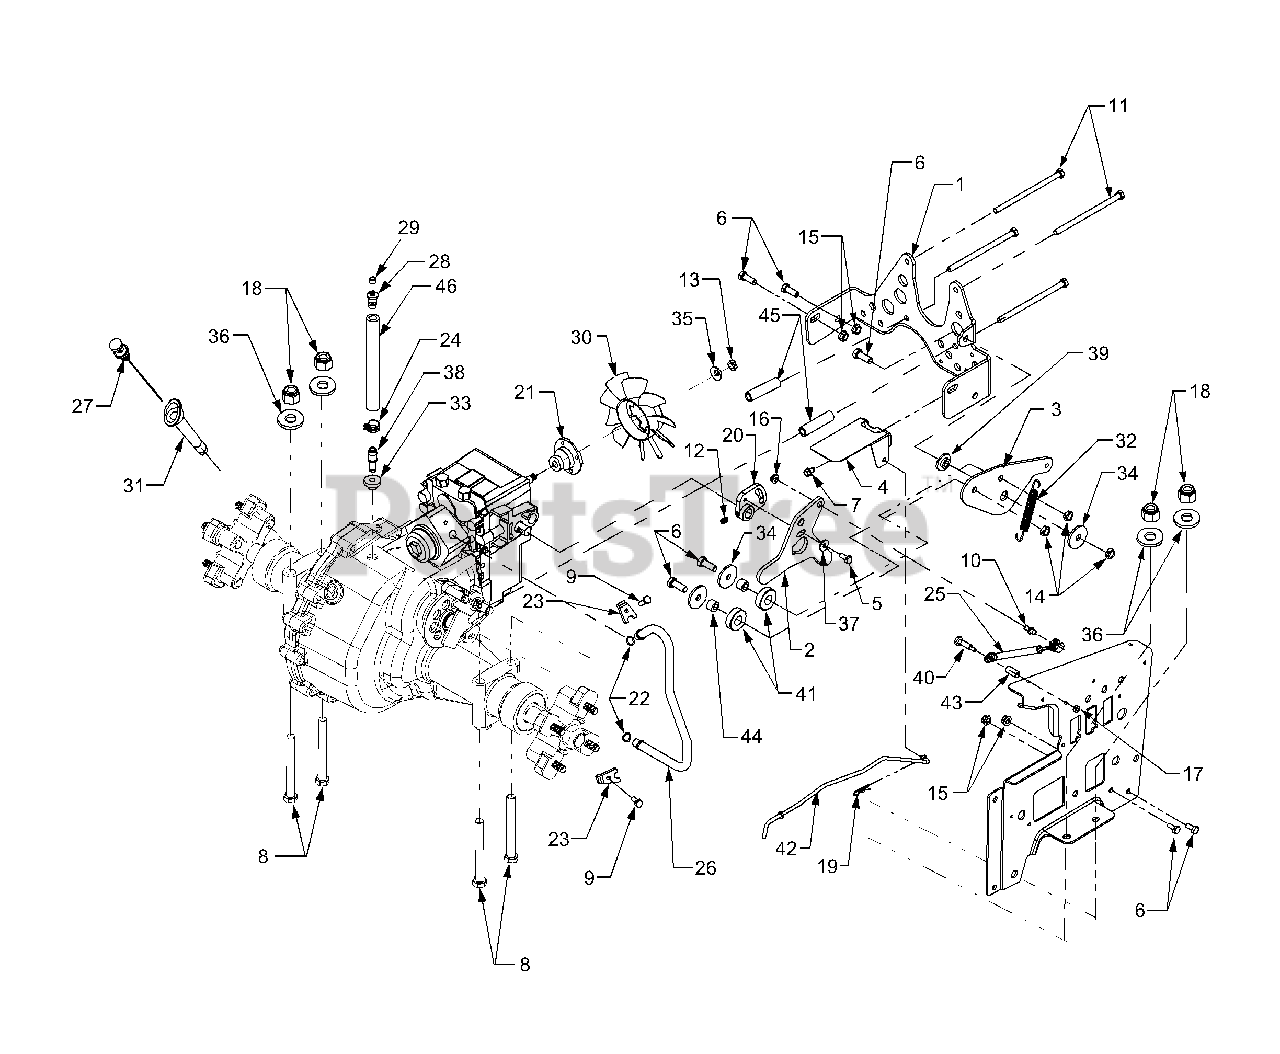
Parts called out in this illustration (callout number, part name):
1	Bracket, Torque
2	Plate, Hydro Neutral Return
3	Link, Neutral Return Bearing
5	Screw, Hex Cap, 1/4-20 x .625 GR5 Lock
6	Screw, Hex Cap, 3/8-16 x 1.0 GR5
7	Screw, Hex Wash. Hd. Tapp, 1/4-20 x .5
8	Screw, Hex Cap, 1/2-20 x 4.5 GR5
9	Screw, Hex Cap, 1/4-20 x .75 GR5
10	Ball Screw, 5/16-18 x .56
11	Screw, Hex Wash. Hd. Tapp, 5/16-18 x 5.5 GR5
12	Screw, Set, 5/16 x .5
13	Nut, Hex Top Lock Jam, 1/2-20
14	Nut, Hex Ctr. Lock Jam, 3/8-16
15	Nut, Hex Flange Lock, 3/8-16
16	Nut, Hex Flange Lock, 5/16-18
17	Nut, Hex, 1/4-20
18	Nut, Hex Insert Lock, 1/2-20
19	Pin, Internal Cotter
20	Arm, Hydro
21	Adapter, Pump
22	O-Ring, .426 ID x .566 OD x .070
23	Clamp, Tube
24	Clamp, Hose
25	Cylinder, Damper
26	Tube, Hydro Pickup
27	Dipstick, Transmission
28	Plastic Vent
30	Fan, Pump
31	Holder, Dipstick
32	Spring, Extension
34	Washer, Flat, .390 x 1.5 x .1
35	Washer, Bell, .5 x 1.0 x .05
36	Washer, Flat, .531 x 1.062 x .134
37	Washer, Flat, .26 x .72 x .06
38	Fitting, Tube
39	Spacer, Shoulder
40	Shoulder Bolt
41	Bearing, Ball
42	Rod, Pump Bypass
43	Spacer, .375 x .5 x 1.02
44	Spacer, .375 x .624 x .445
45	Spacer, Hydro, .3223 x .60 x 2.44
